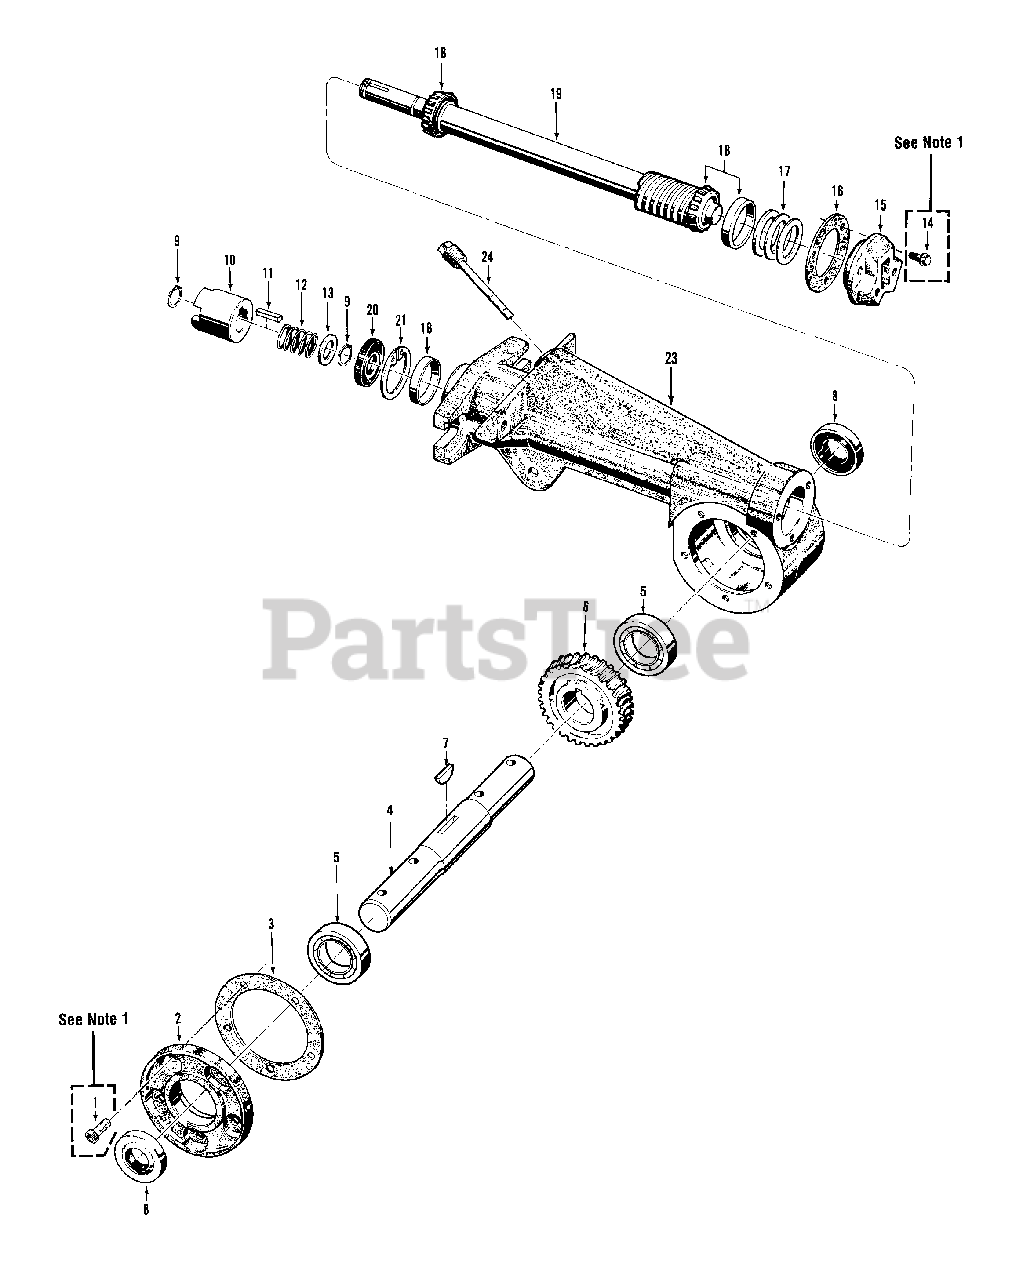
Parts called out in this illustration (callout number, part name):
1	Screw Kit
2	Cover-tiller housing
3	Gasket-tiller housing cover, .010". thick
3	Gasket-same as above, .030" thick
4	Shaft-tiller tine
5	Ball Bearing
6	Worm Gear-bronze, tiller tine shaft
7	Key-tiller tine shaft, woodruff key
8	Seal-oil, tiller tine shaft
9	Retaining Ring-external
10	Dog Clutch-tiller drive shaft
11	Key-3/16" x 1"
12	Spring-dog clutch
13	Shim-dog clutch, 1/16" (.62") thick
14	Screw Kit
15	Cap-rear bearing
16	Gasket-rear bearing cap
17	Shim-front bearing cap, .010" thick
17	Shim-same as above, .030" thick
17	Shim-same as above, .005" thick
17	Shim-same as above, .062" thick
18	Bearing & Cup-sold as set only
19	Shaft-main tiller drive
20	Seal-oil, drive shaft, front
21	Retaining Ring-internal
23	Housing-tiller attachment
24	Dipstick-oil, tiller attachment
